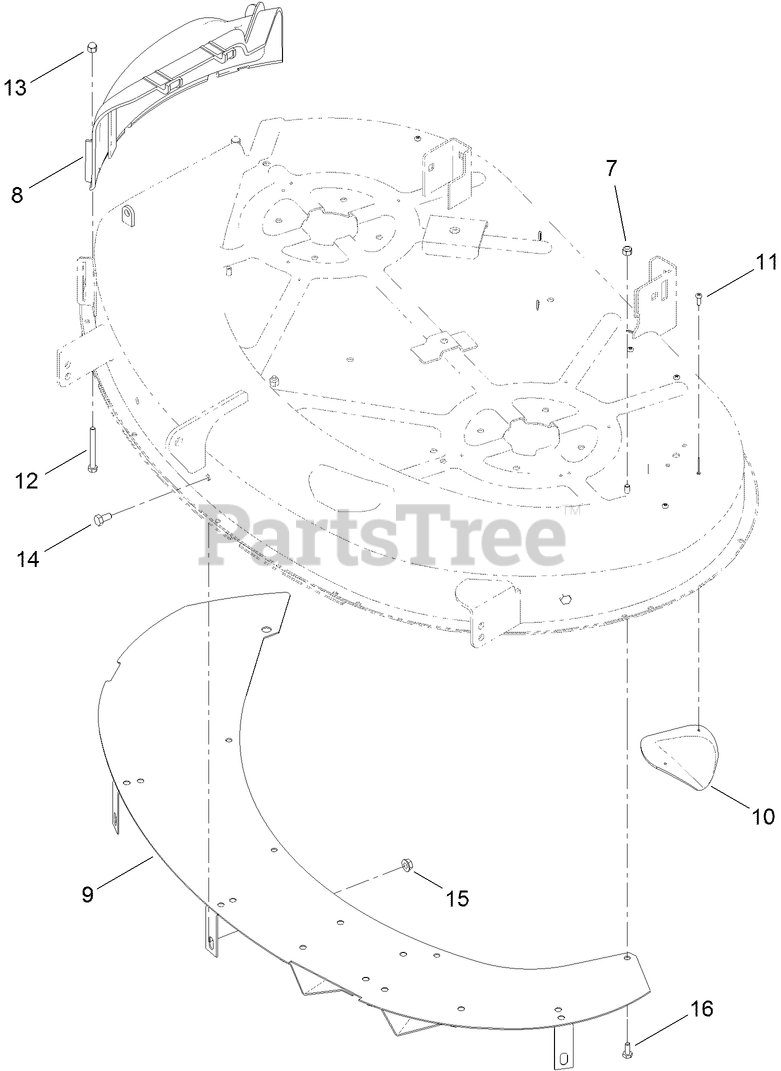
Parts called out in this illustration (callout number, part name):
7	NUT-LOCK, NI
8	COVER-DISCHARGE
9	BAFFLE UPPER ASM
10	PLATE-KICKER
11	SCREW-PPH
12	SCREW-HH
13	NUT-CAP
14	SCREW-HH
15	NUT-HF
16	SCREW-HH
